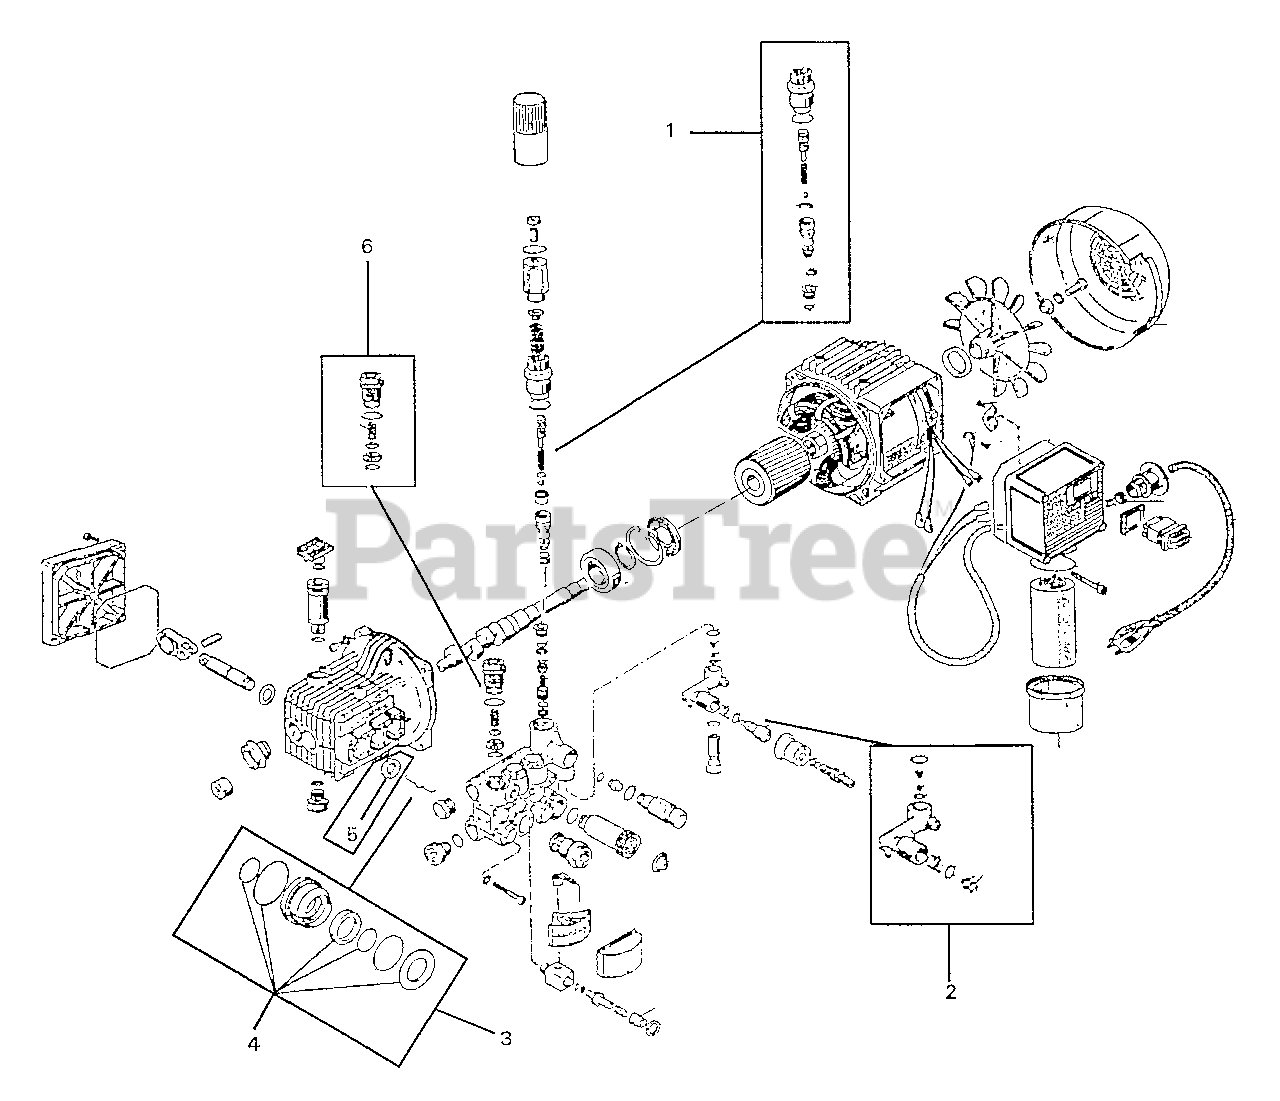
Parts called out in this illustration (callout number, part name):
1	PRESSURE CONTROL VALVE KIT
2	REBUILD RETAINER PACKING KIT
3	RETAINER REBUILD PACKING KIT
4	O-RING KIT
5	OIL SEAL KIT
6	VALVE KIT
